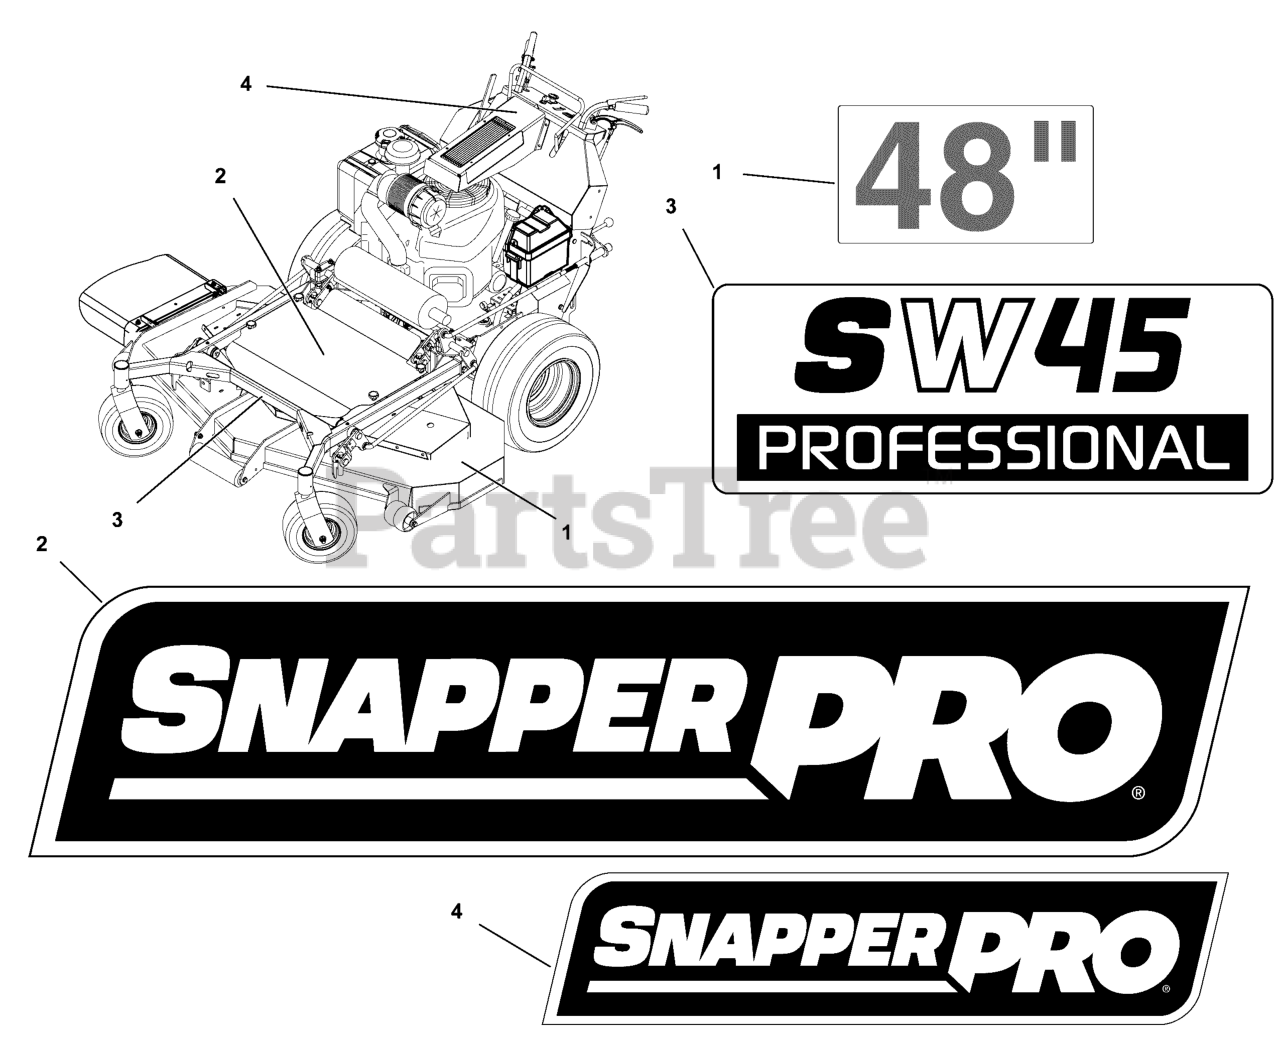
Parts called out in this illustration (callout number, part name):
1	DECAL, 48
2	DECAL, SNAPPER PRO LOGO, LARGE
3	DECAL, MODEL, SW45
4	DECAL, SNAPPER PRO LOGO, X-SMALL
